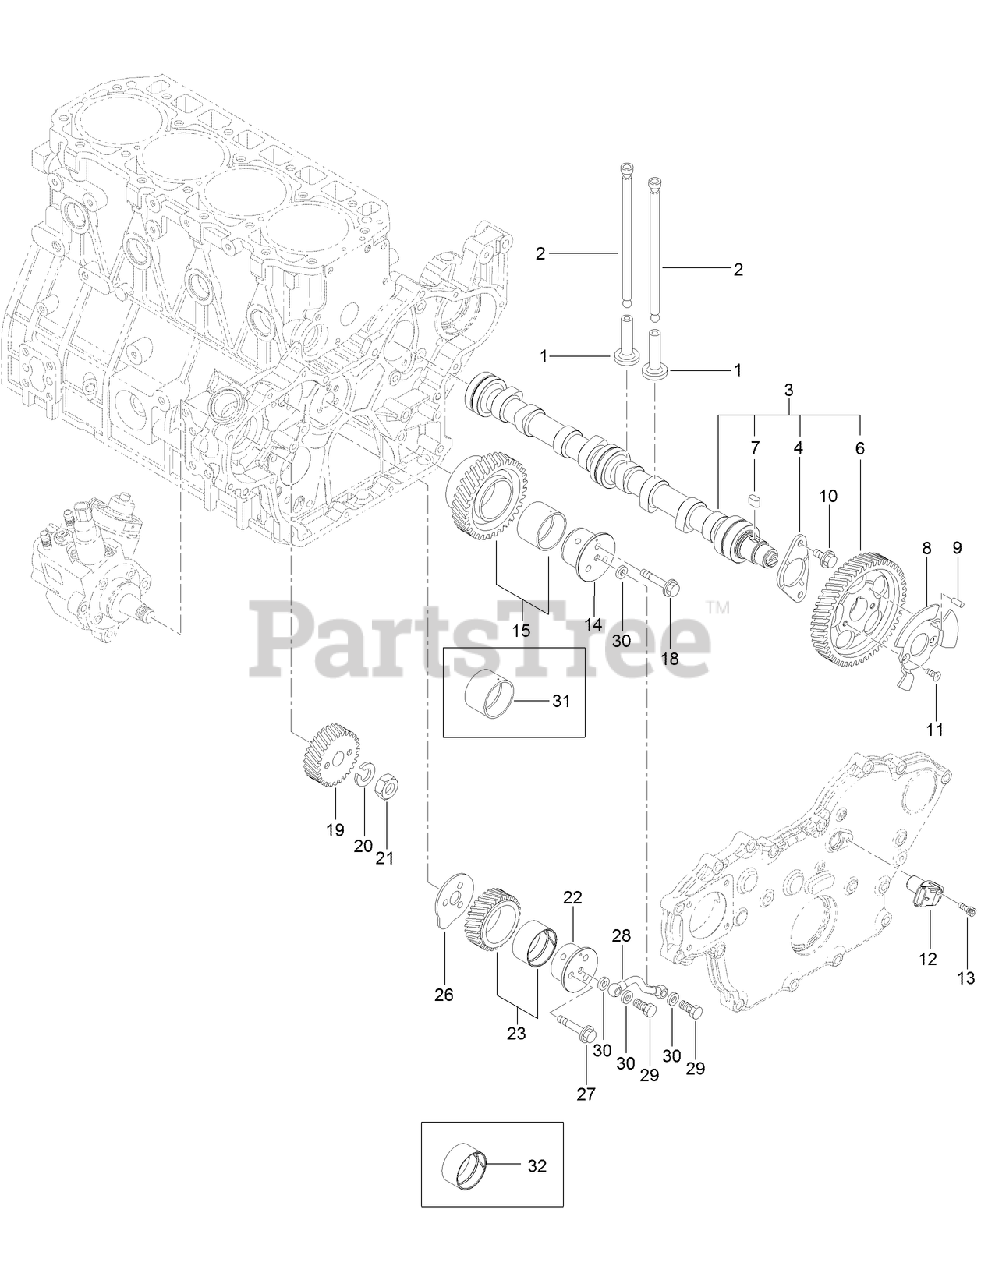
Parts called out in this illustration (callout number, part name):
1	TAPPET
2	ROD-PUSH
3	CAM SHAFT ASM
4	METAL-THRUST
6	GEAR-CAMSHAFT
8	PULSER-GEAR, CAM
9	PIN-SPRING
12	SENSOR-REV, GEAR
14	SHAFT-GEAR A, IDLE
15	IDLE GEAR ASM
19	GEAR-PUMP, SUPPLY
20	WASHER-SPRING
21	NUT-LOCK
22	SHAFT-GEAR B, IDLE
23	IDLE GEAR B ASM
26	PLATE-SHAFT B, IDLE
28	L O PIPE ASM
29	BOLT-JOINT, PIPE
30	WASHER-SEAL
31	BUSHING-GEAR, IDLE
32	BUSHING
